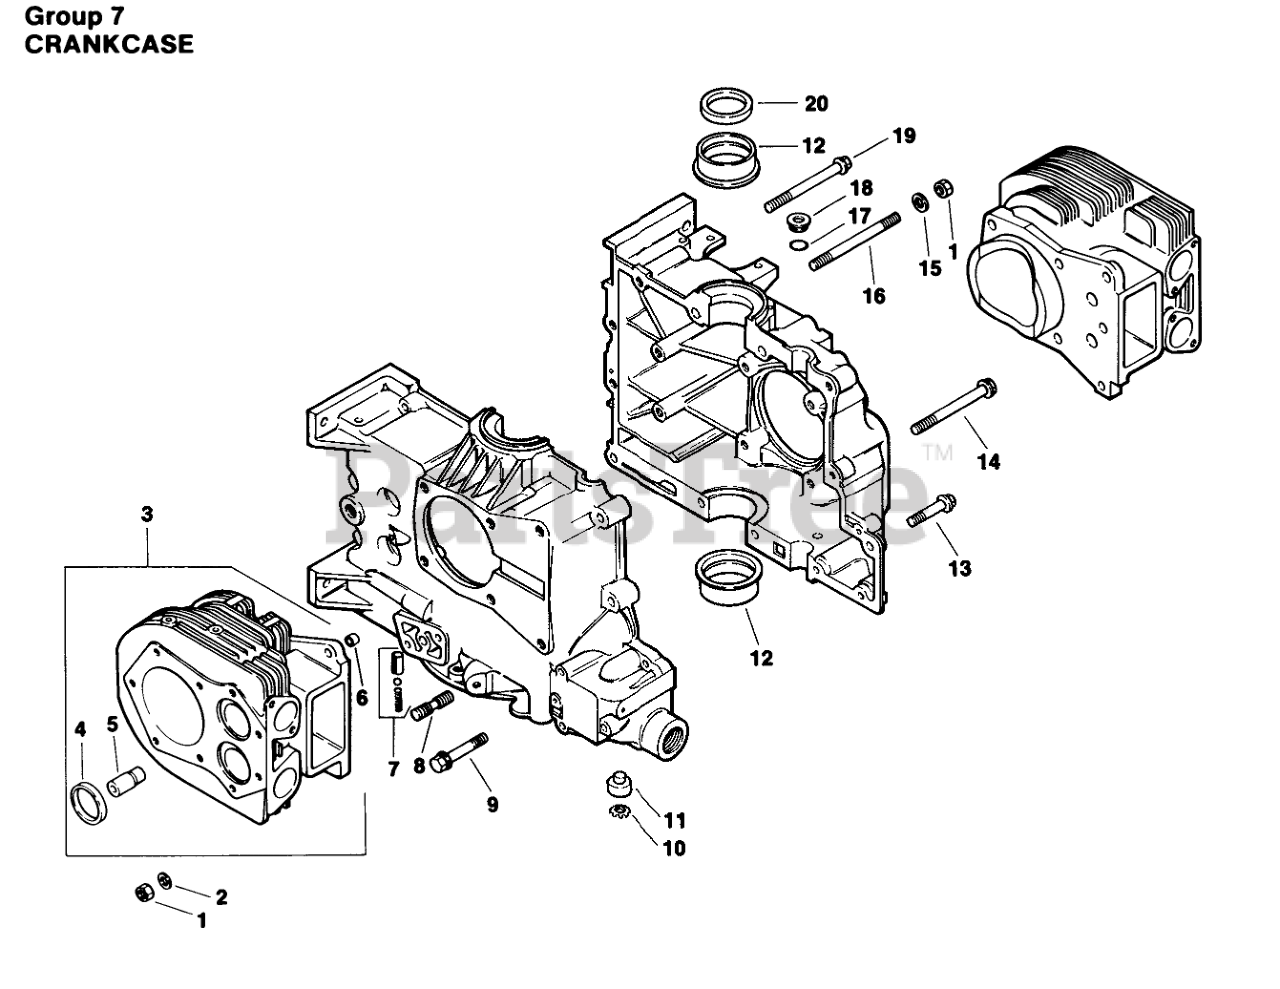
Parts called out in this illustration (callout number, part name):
1	Nut
2	Washer-Flat
3	Kit-Cylinder Barrel (Incl. Ref. #4-6)
4	Insert
5	Guide-Valve
6	Bushing-Locating
7	Kit-Oil Relief
8	Stud-Step
9	Screw-Hex Flange Hd.
10	Ring-Retaining
11	Shaft-Governor
12	Bearing-Sleeve (Std.)
12	Bearing-Sleeve (.010)
12	Bearing-Sleeve (.020)
13	Screw-Hex Flange
14	Screw-Hex Flange
15	Washer-Flat
16	Stud
19	Screw-Hex Flange Hd.
20	Seal-Rear Oil
28	Screw-Hex Washer Hd.
